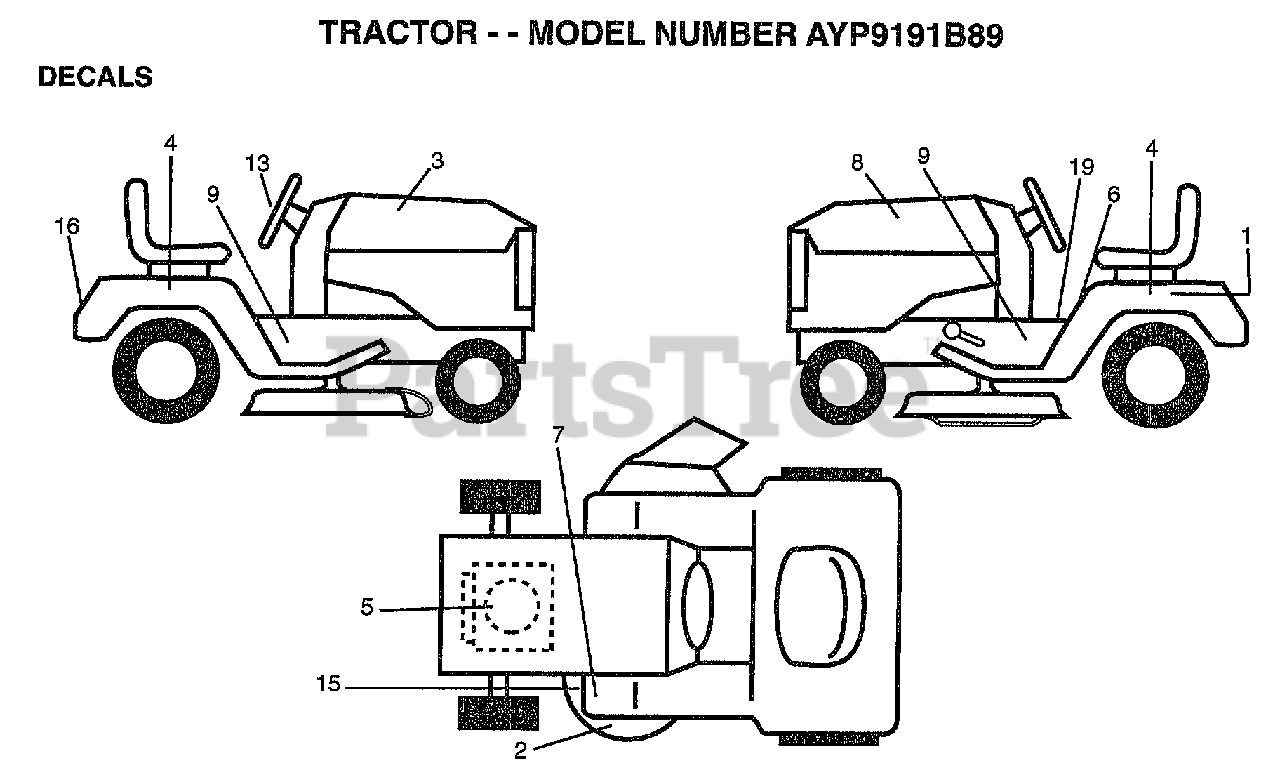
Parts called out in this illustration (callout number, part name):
1	DECAL.BATRY.3-3908
2	DECAL DECK WIZ +
3	DECAL.HOOD.RH
4	DECAL.FENDER.WIZ
5	DECAL HP ENGINE
6	"DECAL DANGER,FEND"
8	DECAL.HOOD.LH
9	"DECAL.CHASSIS.42"""
13	DECAL.INS.STRG.WL
15	"DECAL-SCHEM,BELT"
19	"DECAL INST,SADDLE"
